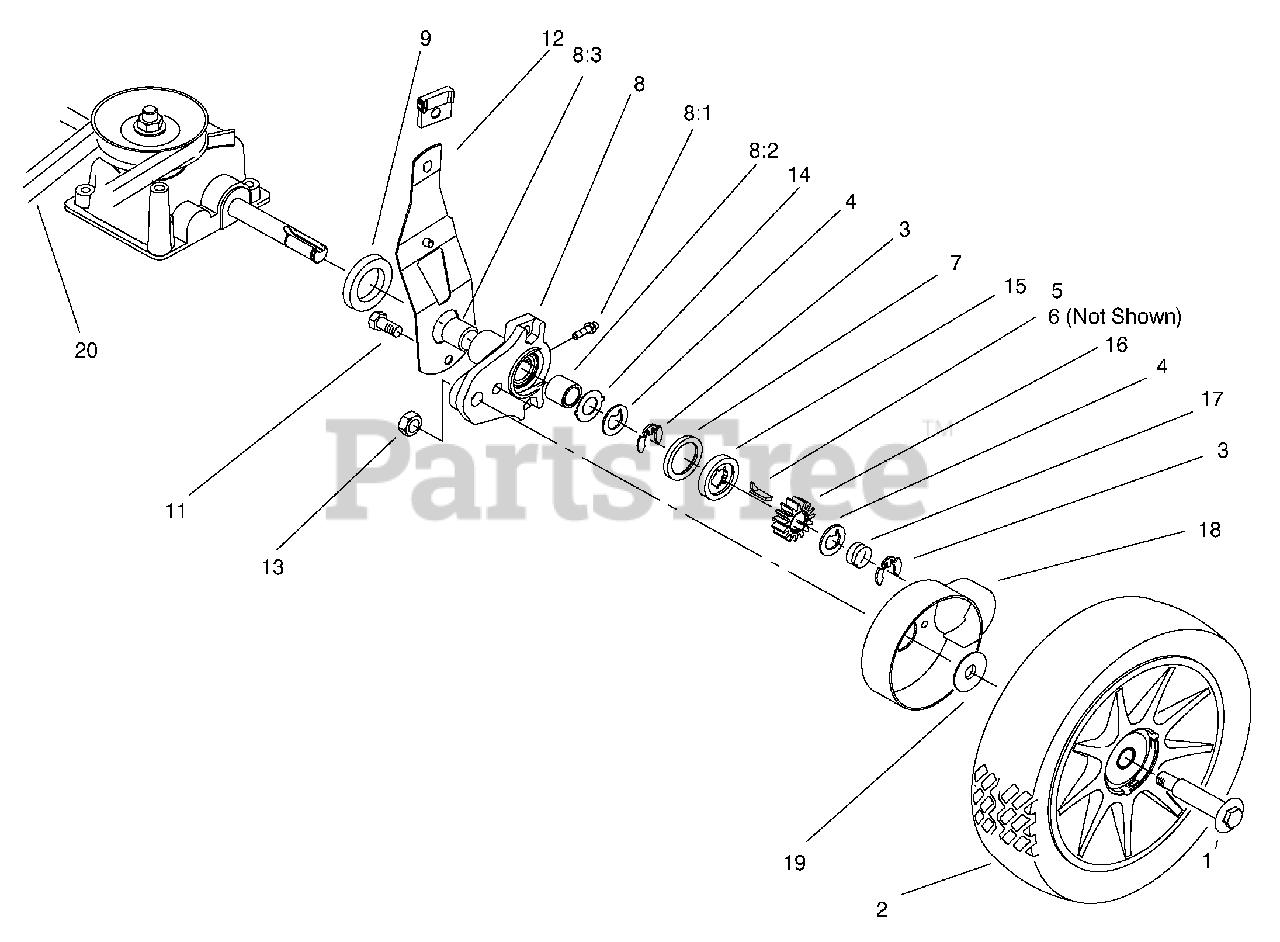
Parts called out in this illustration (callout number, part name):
1	Bolt-Shoulder
2	8" Wheel & Tire ASM.
3	Klip Ring-Special
4	Washer-Keyed Thrust
5	Key-Rocking LH
6	Key-Rocking
7	Ring-Friction
8	ASM-Hgt Adj Arm, Rear
8:1	Fitting-Zerk
9	Spacer-Axle Shaft
12	Spring Arm ASM-Rear
13	Nut-Jam, Locking
14	Washer-Pivot Arm
16	Pinion-Gear, 15t
17	Spring-Compression
18	Cover-Wheel
19	Washer-Stepped
